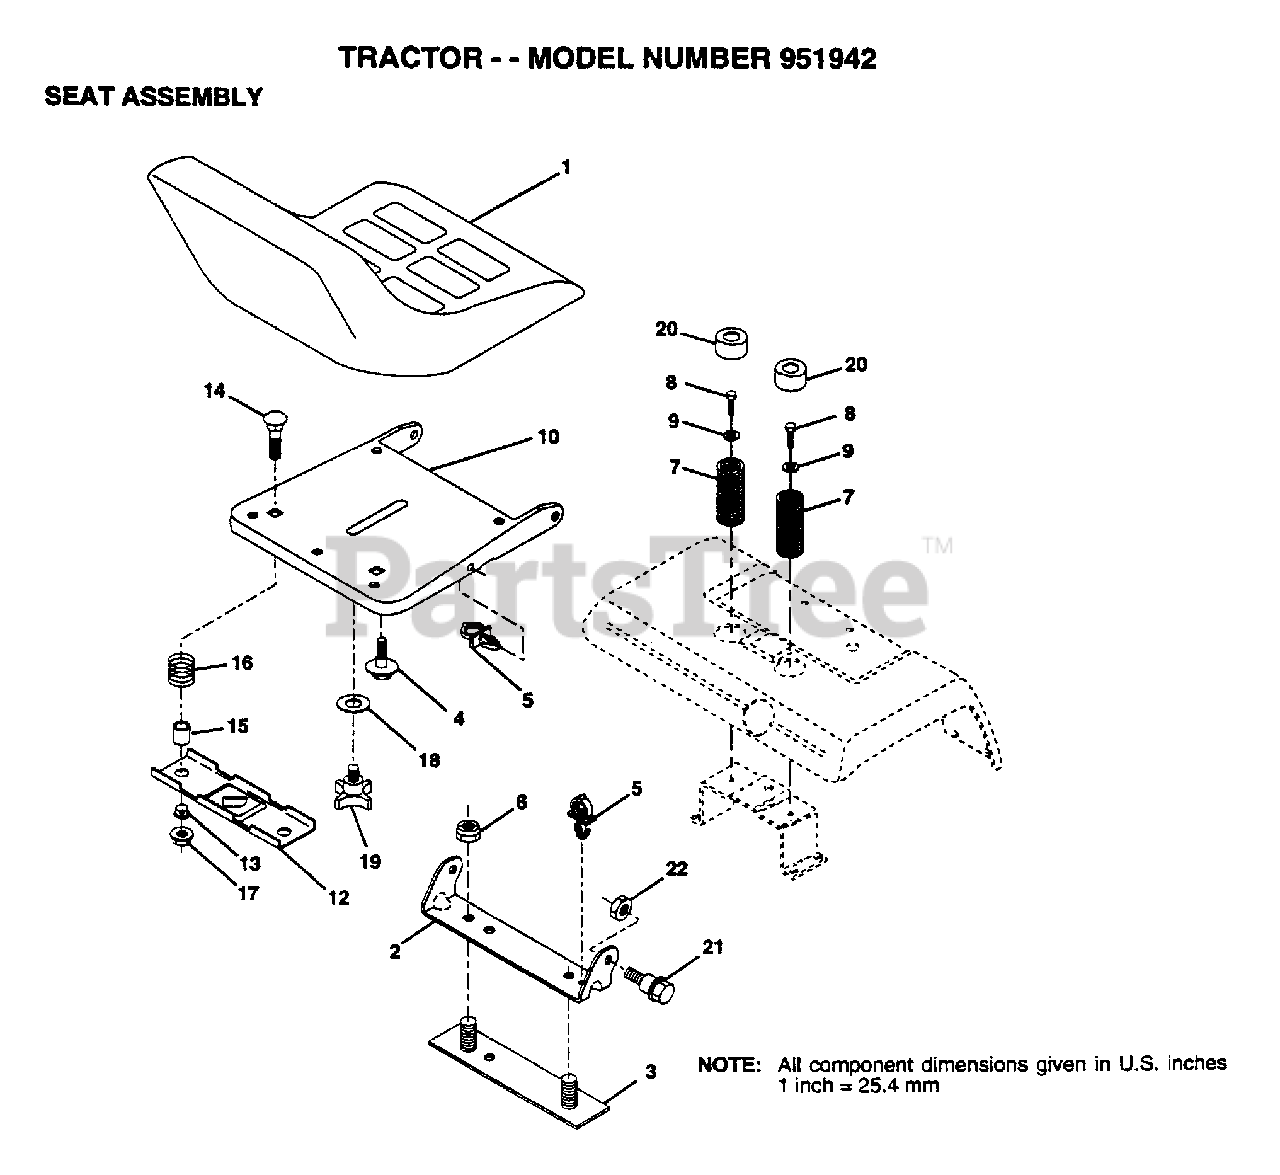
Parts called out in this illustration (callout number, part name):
2	BRACKET PVT SEAT
3	STRAP ASM FENDER
4	"BOLT,SHOULDER"
5	CLIP.PUSH-IN.HING
7	SPRING COMPRESSIO
8	SCREW LT
9	WASHER
12	BRKT SWITCH
13	BUSHING
15	SPACER SPLIT
16	SPRING COMPRESSED
18	WASHER
19	"KNOB 1/2"" YT"
20	CAP SPRING
21	BOLT.SHLD.5/16-18
